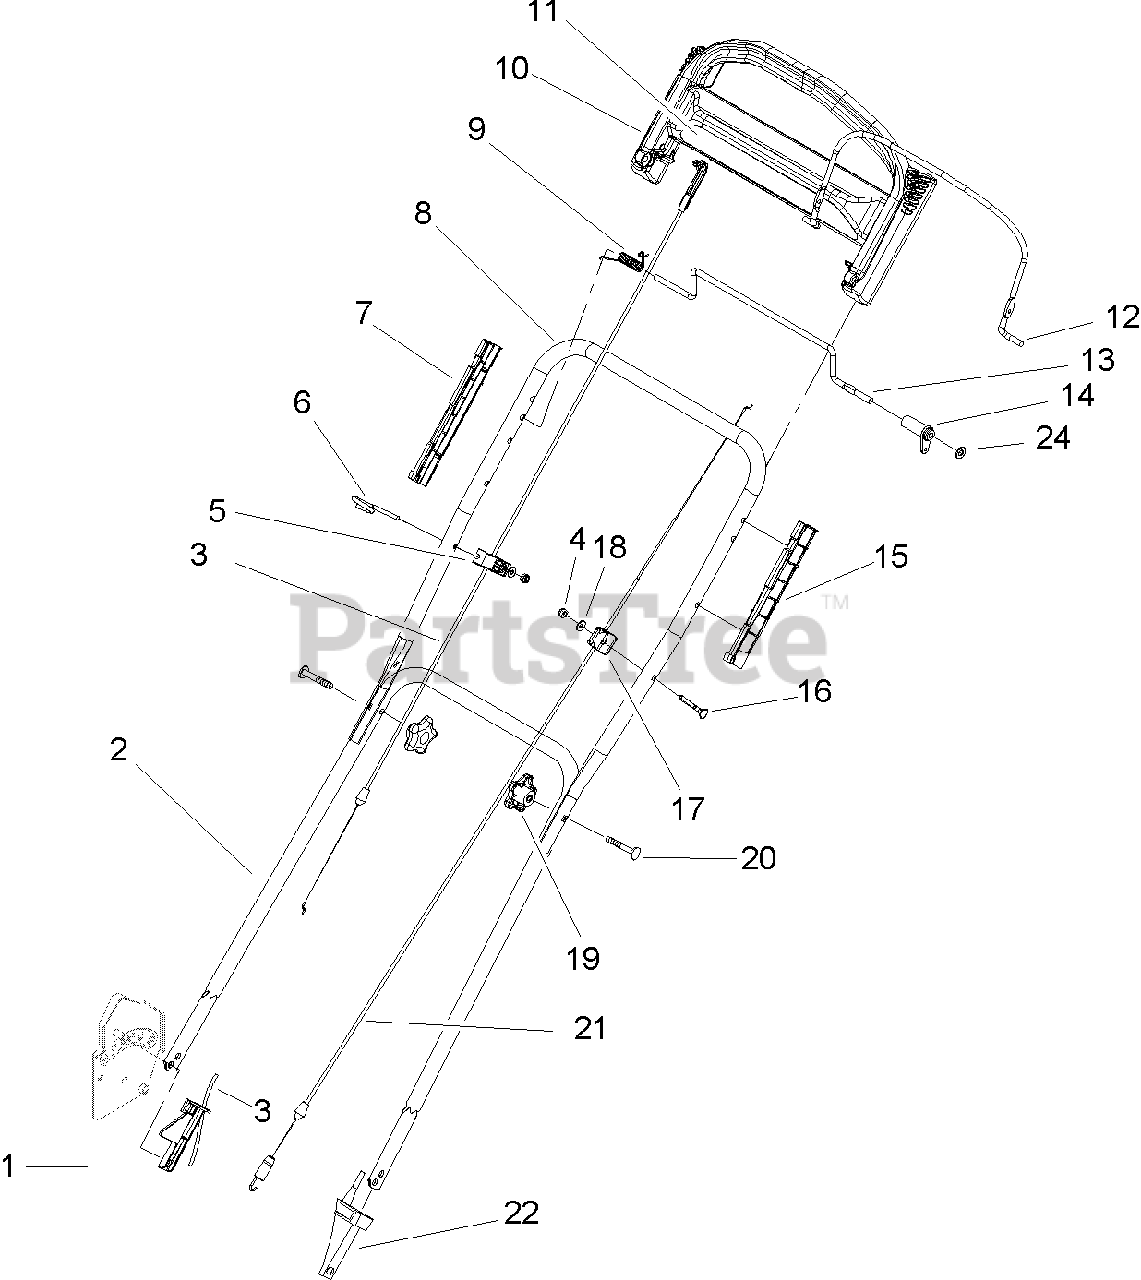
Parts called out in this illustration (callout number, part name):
1	GUARD-CABLE
2	HANDLE-LOWER
3	CABLE-BRAKE
4	NUT-LOCK, NI
5	ANCHOR-CABLE
6	GUIDE-ROPE
8	HANDLE-UPPER
9	Spring-Torsion
10	HANDLE-CONTROL
11	DECAL-HANDLE
12	Bail-Brake
13	BAR-CONTROL, TRACTION
14	LEVER-TRACTION
17	ANCHOR-CABLE, UPPER
18	WASHER-FLAT
19	KNOB-HANDLE
21	Cable-Traction
22	ANCHOR-CABLE
24	WASHER-FLAT
